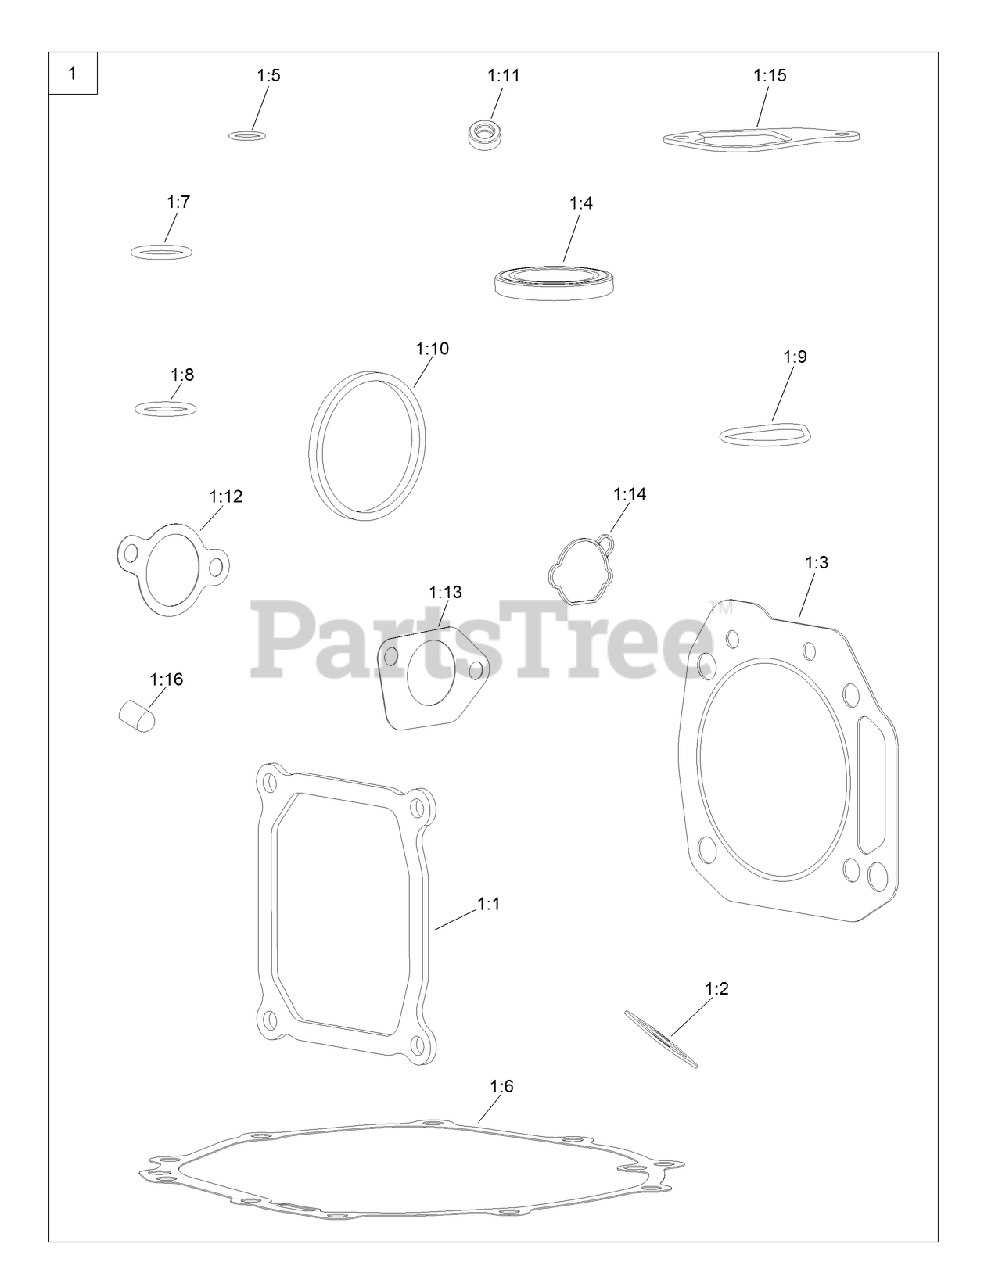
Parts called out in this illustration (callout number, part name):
1	GASKET AND SEAL KIT
1:1	GASKET-COVER, VALVE
1:2	GASKET-EXHAUST
1:3	GASKET-CYCLINDER
1:4	SEAL-OIL
1:5	O-RING
1:6	GASKET-CRANKCASE
1:7	O-RING
1:8	O-RING
1:9	SEAL-PUMP, OIL
1:10	SEAL-ADAPTOR, OIL
1:11	SEAL-OIL
1:12	GASKET-CARBURETOR
1:13	GASKET-CARBURETOR
1:14	GASKET-CARBURETOR
1:15	GASKET-BREATHER
1:16	CAP-SEAL
